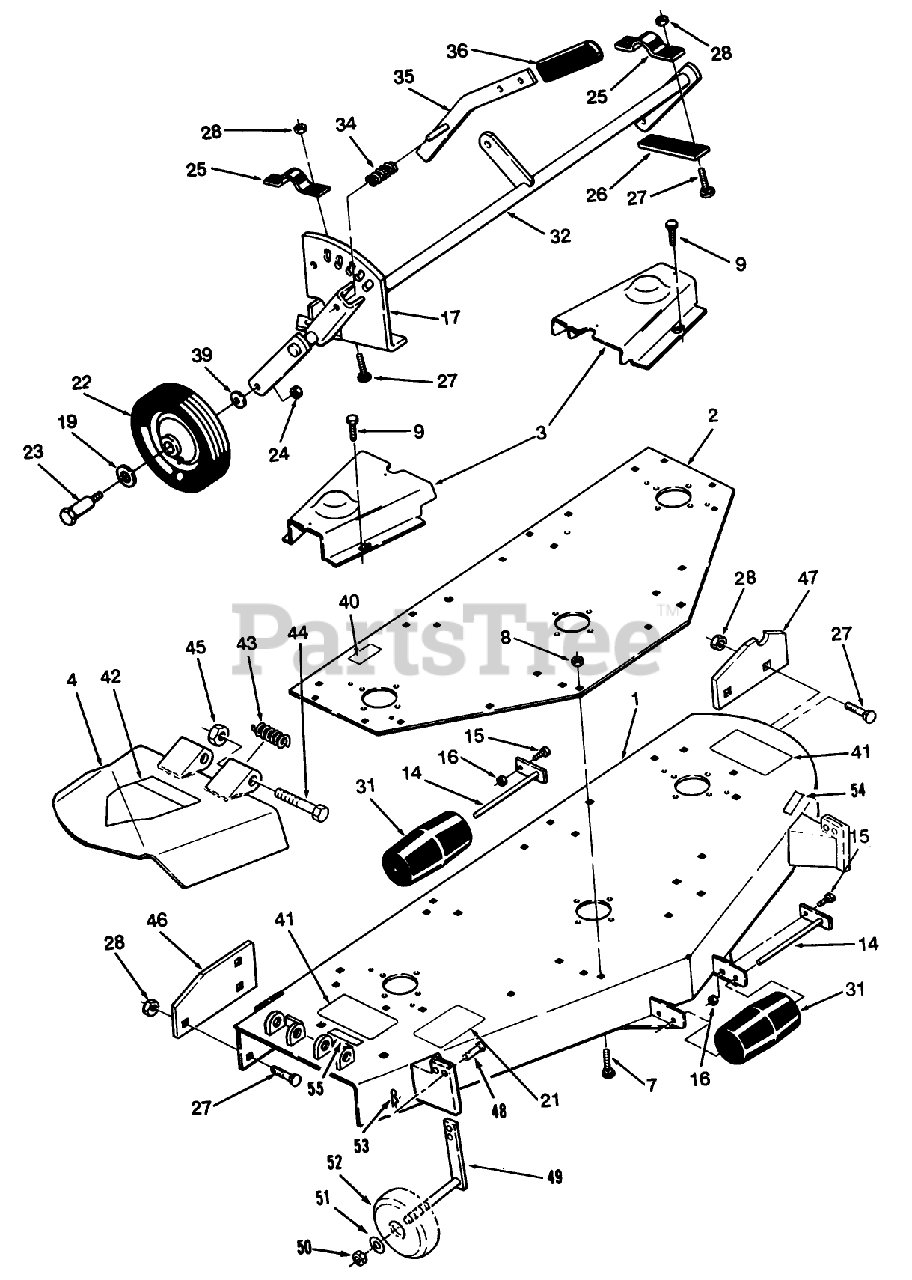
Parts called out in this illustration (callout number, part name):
1	Deck
2	PLATE-TOP REINFOR R
3	Belt Cover
4	Chute Guard Assembly
7	BOLT-CARR
8	NUT-LOCK, NI
9	Bolt
14	ROLLER-SHAFT
15	Bolt
16	NUT-LOCK, NI
17	Quadrant
19	WASHER-FLAT
21	DECAL-BELT INSTALL
22	ASSY-GAUGE WHEEL
23	SCREW-HH
24	NUT-LOCK, NI
25	Clamp
27	BOLT-CARR
28	NUT-LOCK, NI
31	ROLLER-ANTI SCALP
32	Gage Wheel Support
34	SPRING-COMPRESSION
35	Lever
39	SPACER
40	DECAL-HOC
41	DECAL-DANGER, THROWN OBJECT
42	DECAL-DANGER
43	SPRING
44	SCREW-HH
45	NUT-LOCK, NI
46	Wear Plate RH
47	PLTE WEAR LH
48	Pin-Clevis
49	GAGE-WHEEL
50	NUT-LOCK, NI
51	WASHER-FLAT
52	WHEEL-GAGE
53	Hairpin
54	DECAL - WHEEL ADJUSTMENT
55	DECAL-DANGER
